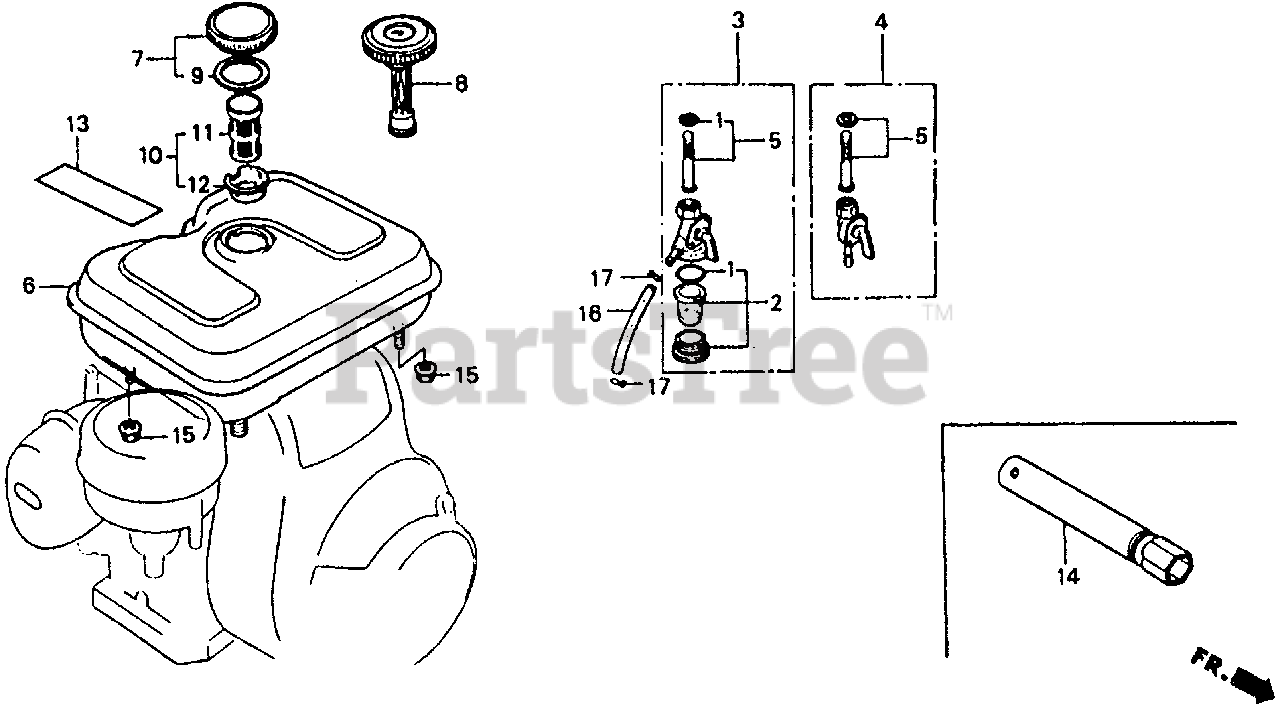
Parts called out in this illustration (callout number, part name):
1	GASKET SET, VALVE
2	CUP SET, FUEL STRAINER
3	PETCOCK ASSY.
5	SCREEN SET
6	TANK, FUEL *NH31* (MCKINLEY WHITE)
7	CAP, FUEL FILLER
8	GAUGE, FUEL (ENGLISH)
8	GAUGE, FUEL
9	GASKET, FUEL FILLER CAP
10	FILTER, FUEL
11	FILTER, FUEL
12	HOLDER, FUEL FILTER
13	MARK, CAUTION (ENGLISH/FRENCH)(SPANISH)
14	WRENCH, SPARK PLUG
15	NUT, FLANGE (6MM)
16	BULK HOSE, FUEL (4.5X3000) (4.5X70)
17	CLIP, TUBE (B8)
